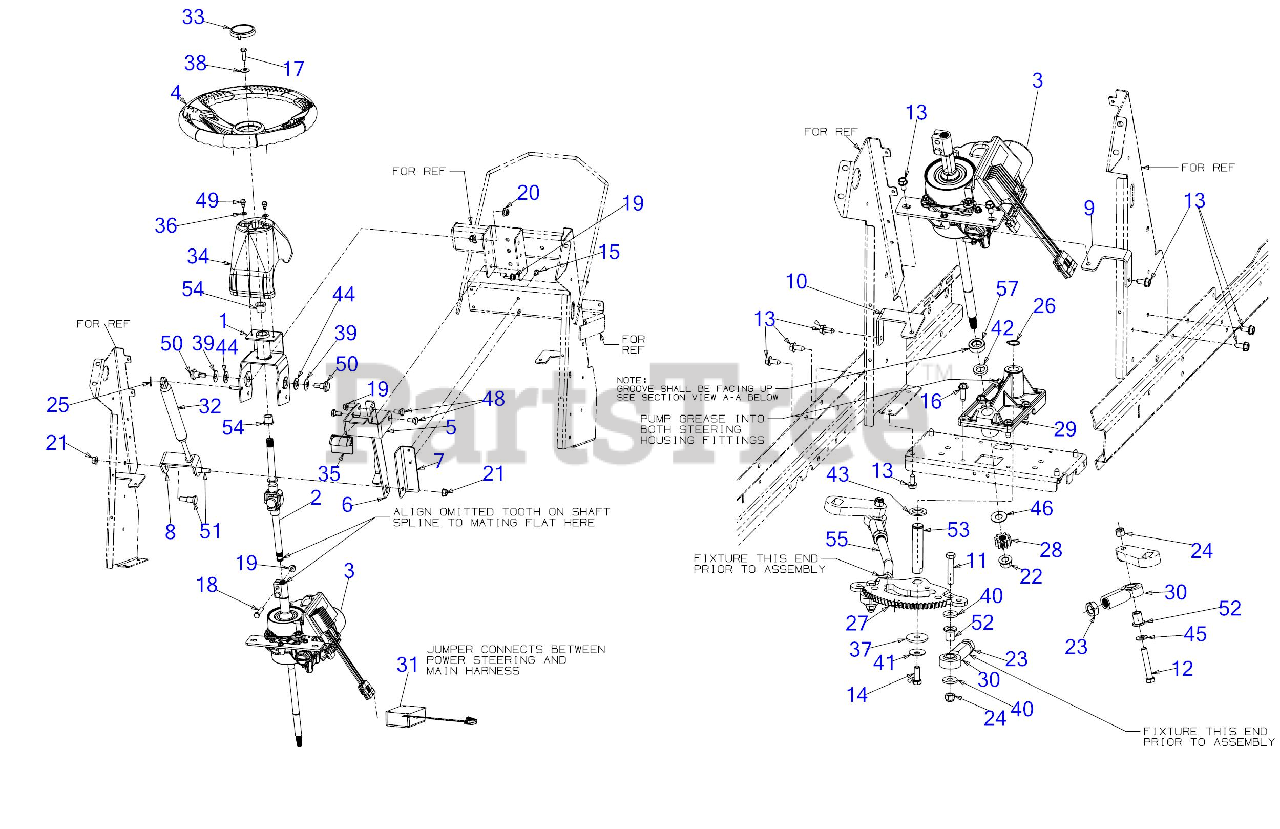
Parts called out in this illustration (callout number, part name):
1	UPPER STEERING BRACKET ASSEMBLY
2	UPPER STEERING SHAFT ASSEMBLY
3	EPS POWER STEERING TRANSMISSION ASSEMBLY
4	STEERING WHEEL
5	TILT LEVER BRACKET
6	TILT ENGAGE BRACKET
7	TILT STEERING BRACKET
8	DAMPER CYLINDER PIVOT BRACKET
11	HEX SCREW 3/8-24 X2.00
12	HEX SCREW 3/8-24 x 2.25 GR5
13	SCREW 5/16-18 x .750
14	SCREW 3/8-24 x 1.00 GR5
15	SCREW 1/4-20 X.500
16	SCREW 5/16-18 x 1.00
17	SCREW 5/16-18 x 1.00 GR5
18	BOLT 5/16-18X1.375 GR5
19	FLANGE LOCK NUT 5/16-18
21	HEX LOCK NUT
22	FLANGE LOCK NUT
23	HEX JAM NUT 5/8-18
24	INSERT NUT
25	COTTER PIN 3/32
26	SNAP RING
27	STEERING GEAR SEGMENT
28	STEERING PINION GEAR
29	STEERING HOUSING ASSEMBLY
30	BALL JOINT ROD END
31	VOLT PROTECTOR HARNESS EPS PURPLE
32	DAMPER CYLINDER
33	STEERING WHEEL CAP
34	STEERING COLUMN
35	TILT WHEEL LEVER
36	FLAT WASHER .344 ID x .62 OD x .033
37	FLAT WASHER .390x1.500x.134
38	BELL WASHER .337 X.867 x .057
39	BELL WASHER
40	FLAT WASHER .385 x 1.00 x .135
41	BELL WASHER .390x1.130x.062
42	FLAT WASHER .632X1.00X.16
43	SHIM WASHER .76X1.25X.10
44	FLAT WASHER
45	FLAT WASHER
46	FLAT WASHER
48	SHOULDER SCREW .437
49	SHOULDER SCREW 1/4-20X.50 19"PSH
50	BOLT-SHLDR .49 DIA x .50
51	SHOULDER BOLT .50 DIA x .66
52	SHOULDER SPACER
53	STEERING SHAFT SEGMENT
54	FLANGE BEARING
55	STEERING DRAG LINK (LH)
55	STEERING DRAG LINK (RH)
57	WIRE RING SPACER HUB
